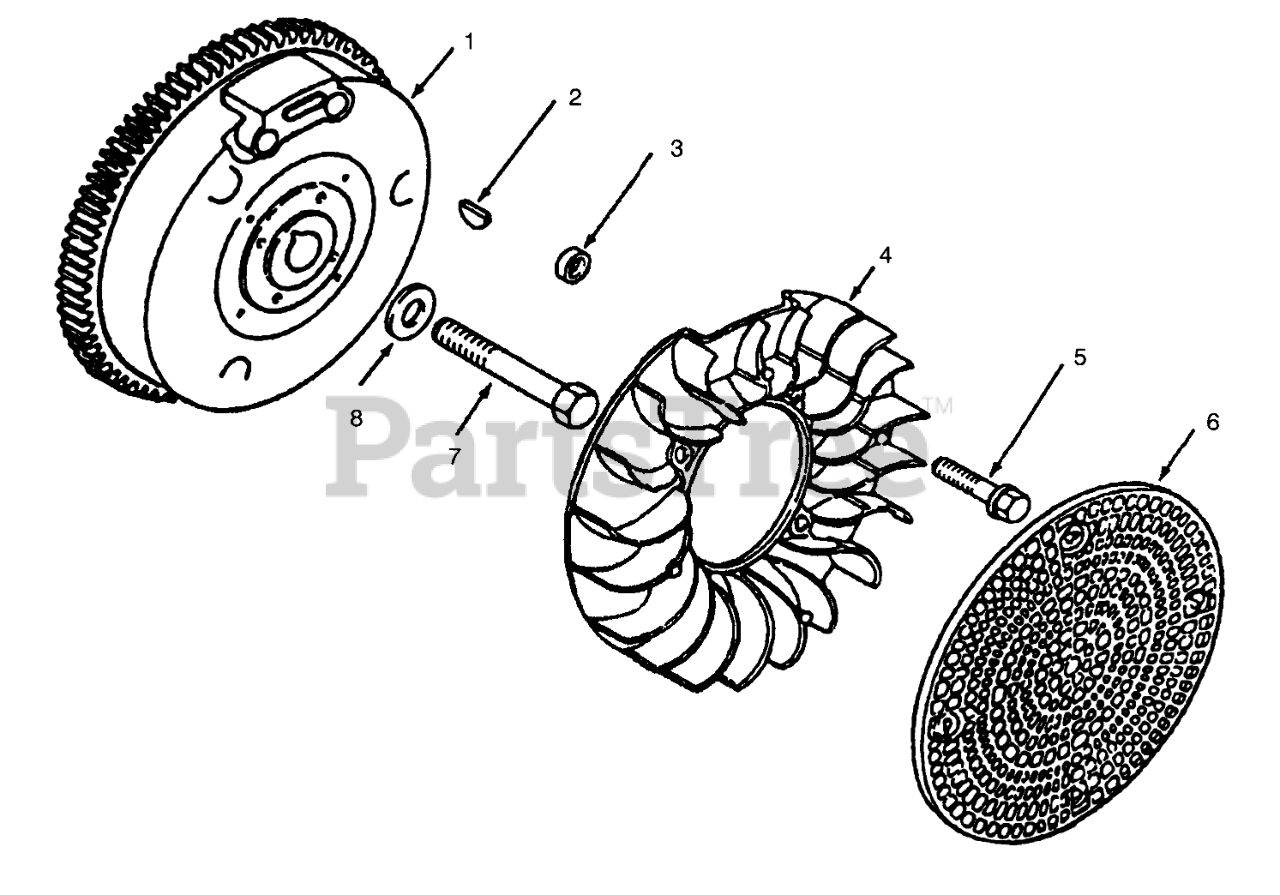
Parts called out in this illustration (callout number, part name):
1	Flywheel
2	Key-Woodruff
3	Spacer
5	Screw-Hex. Hd.
6	Screen
7	Screw
8	Washer
